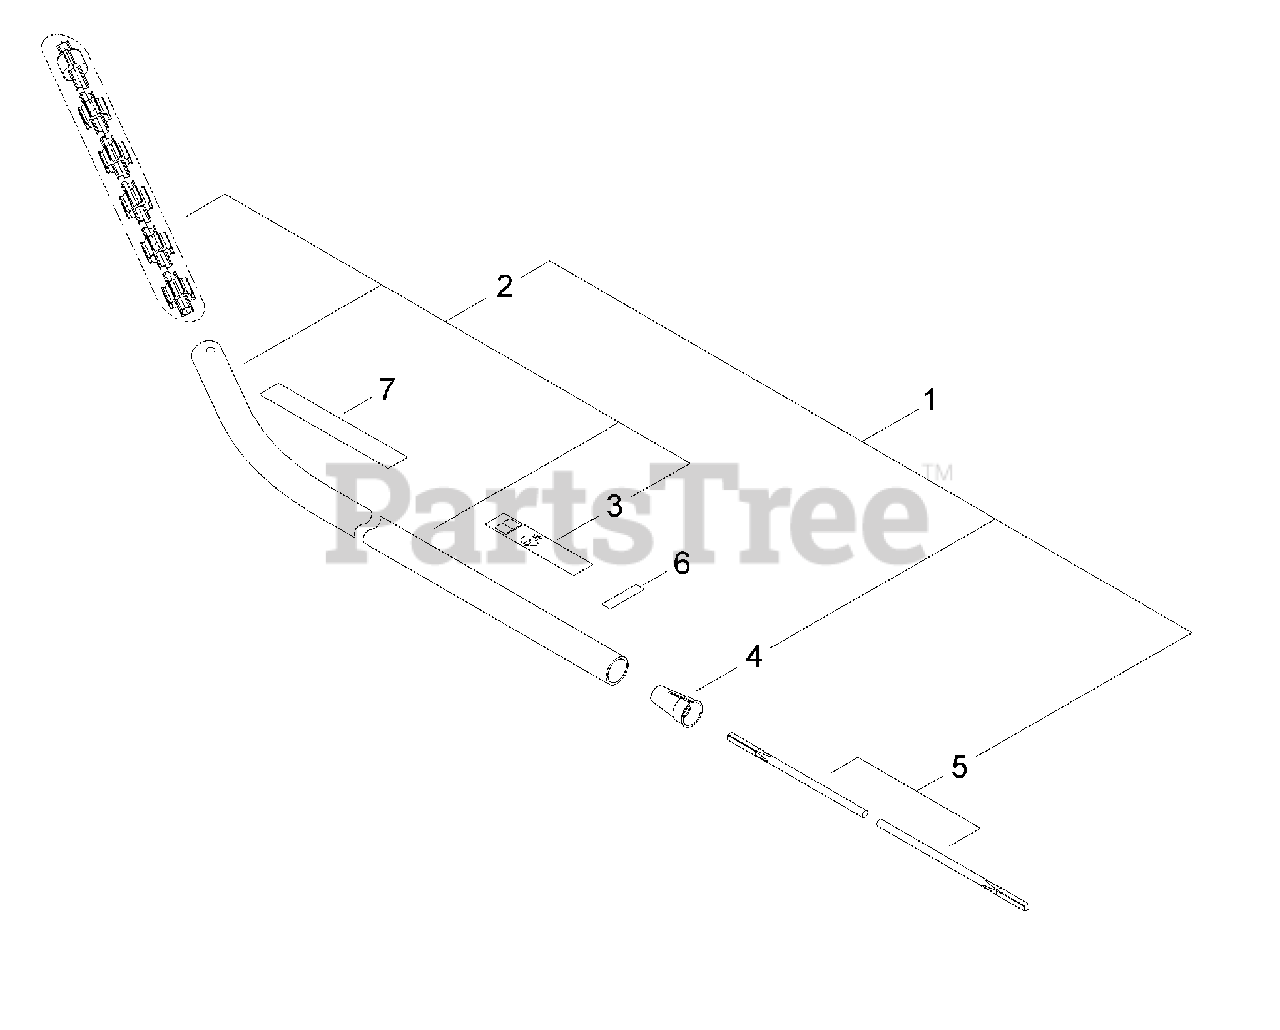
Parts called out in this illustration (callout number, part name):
1	OUTER TUBE ASSY
2	OUTER TUBE ASSY
3	LABEL - CAUTION
4	GUIDE, SHAFT
5	DRIVESHAFT - FLEXIBLE
6	LABEL - INSTRUCTION
7	LABEL - SWISHER E4
